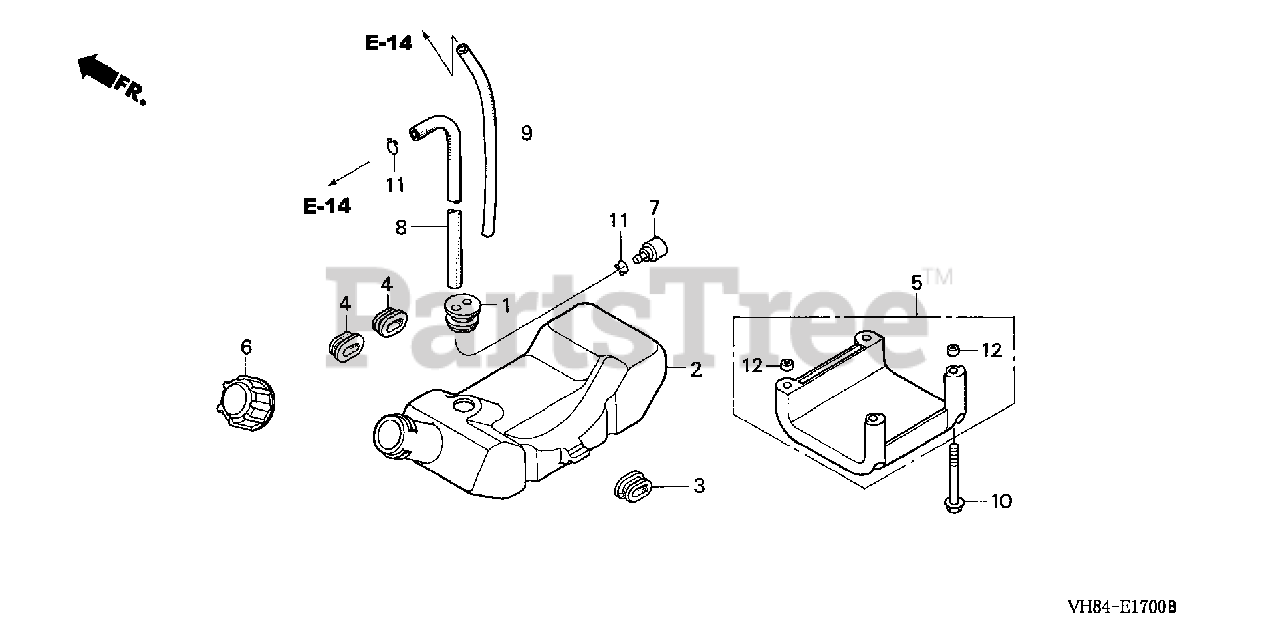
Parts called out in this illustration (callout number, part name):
1	GROMMET, FUEL TUBE
2	TANK, FUEL
3	RUBBER A, TANK MOUNTING
4	RUBBER A, TANK MOUNTING
4	RUBBER B, TANK MOUNTING
5	GUARD, TANK
6	CAP ASSY., FUEL TANK
7	FILTER, FUEL
8	TUBE, FUEL
9	TUBE, FUEL RETURN
10	BOLT, FLANGE (5X14) (CT200)
11	CLIP, TUBE
12	COLLAR, TOP COVER
